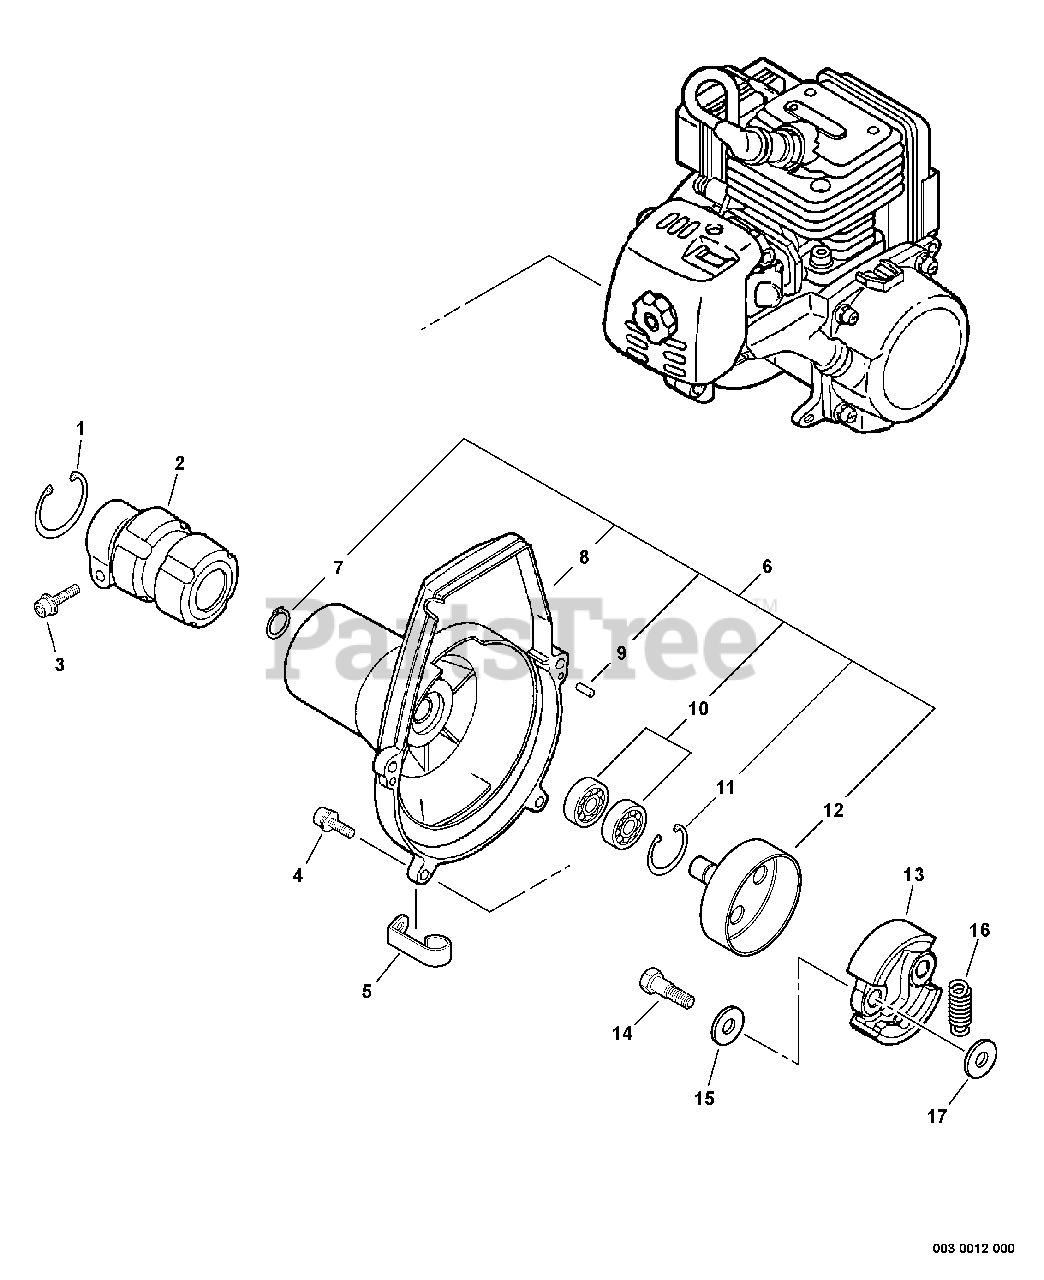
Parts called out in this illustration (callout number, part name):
1	RING, SNAP Ø42
2	HOLDER, MAIN PIPE
3	BOLT 5×28
4	BOLT 5×18
6	FAN CASE ASSY
7	RING, RETAINING - 12
8	FAN CASE ASSY - ORANGE
9	PIN, LOCATING 4
10	BEARING, BALL 6001
11	RING, SNAP 28
12	DRUM, CLUTCH
13	SHOE, CLUTCH
14	BOLT, CLUTCH 8×7.9×M6
15	WASHER, SPRING 8.5×16×0.5
16	SPRING, CLUTCH
17	WASHER 6.2×19×1.0
